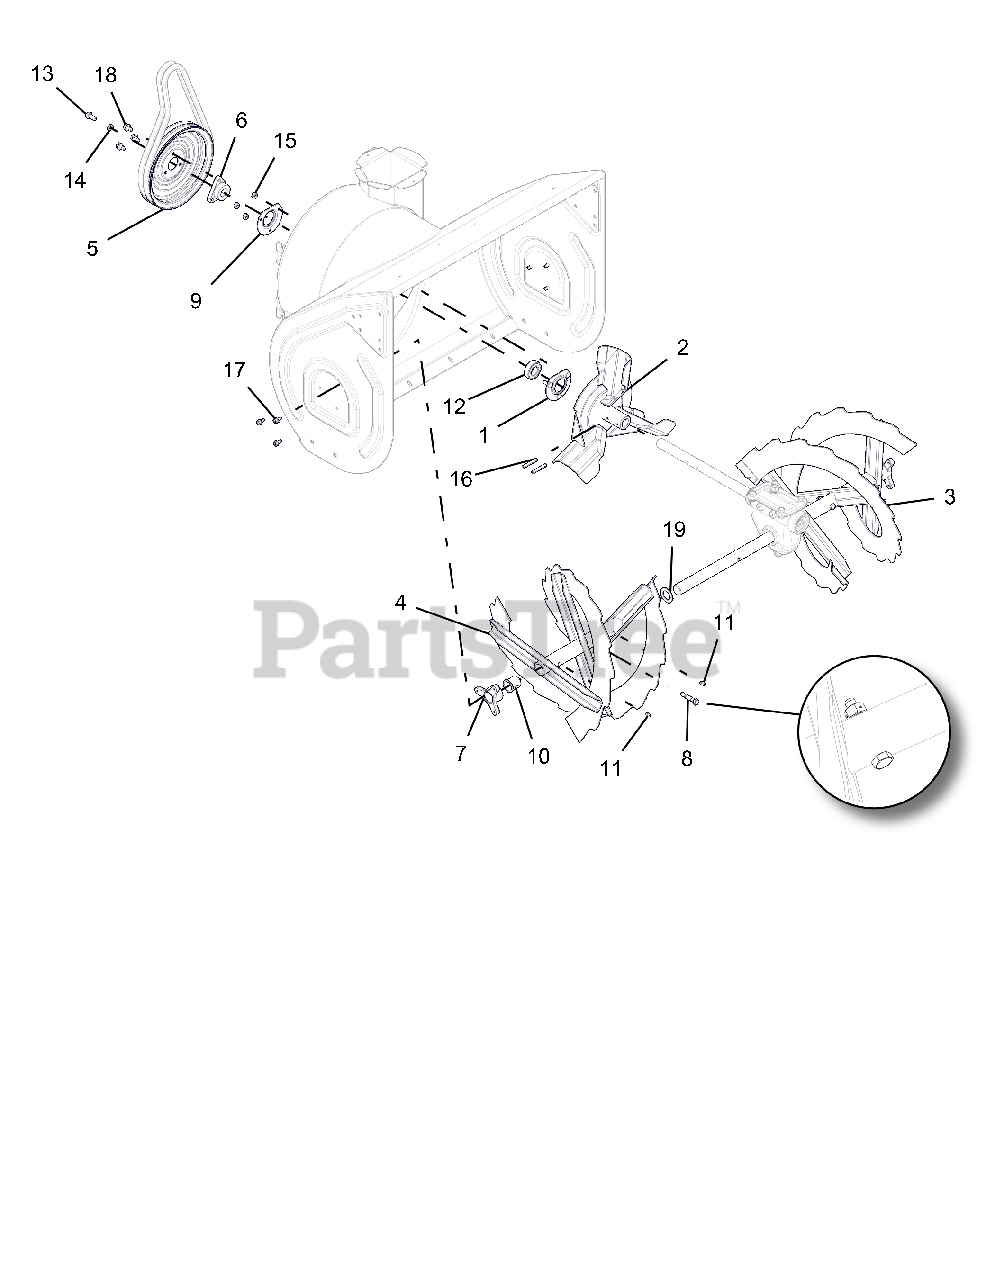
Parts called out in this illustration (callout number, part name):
1	BEARING FLANGE
2	IMPELLER, 3 BLADE-14"
3	RAKE, LH-28"(1 ID X 15.75 OD)
4	RAKE, RH-28"(1 ID X 15.75 OD)
5	PULLEY, SPIN FORM DUAL GROOVE
6	PULLEY HUB, D-BORE .87 PRO
7	BUSHING, RAKE SHAFT 1"
8	SHEAR BOLT SERVICE ASSEMBLY
9	BEARING FLANGE
10	BSHG-FLG SPLIT NYLINER 1.0" HP
11	ZERK,FITTING .25X.125 DRIVE IN
12	BRG-BALL .876X1.75X.50 RSTFP
13	BLT-HEX .31-24X.75 YWZC GR5
14	WSHR-LK .312X.097 HVY YWZC
15	@NUT-LK-CTR .25-20 YWZC
16	PIN-ROLL .250X1.75
17	SCR-TAP .25-20X.50 HWH TR YWZ
18	@SCR-TAP .31-18X.50 HWH TR YWZ
19	WSHR-FL-STL 1.010X1.505X.062YZ
